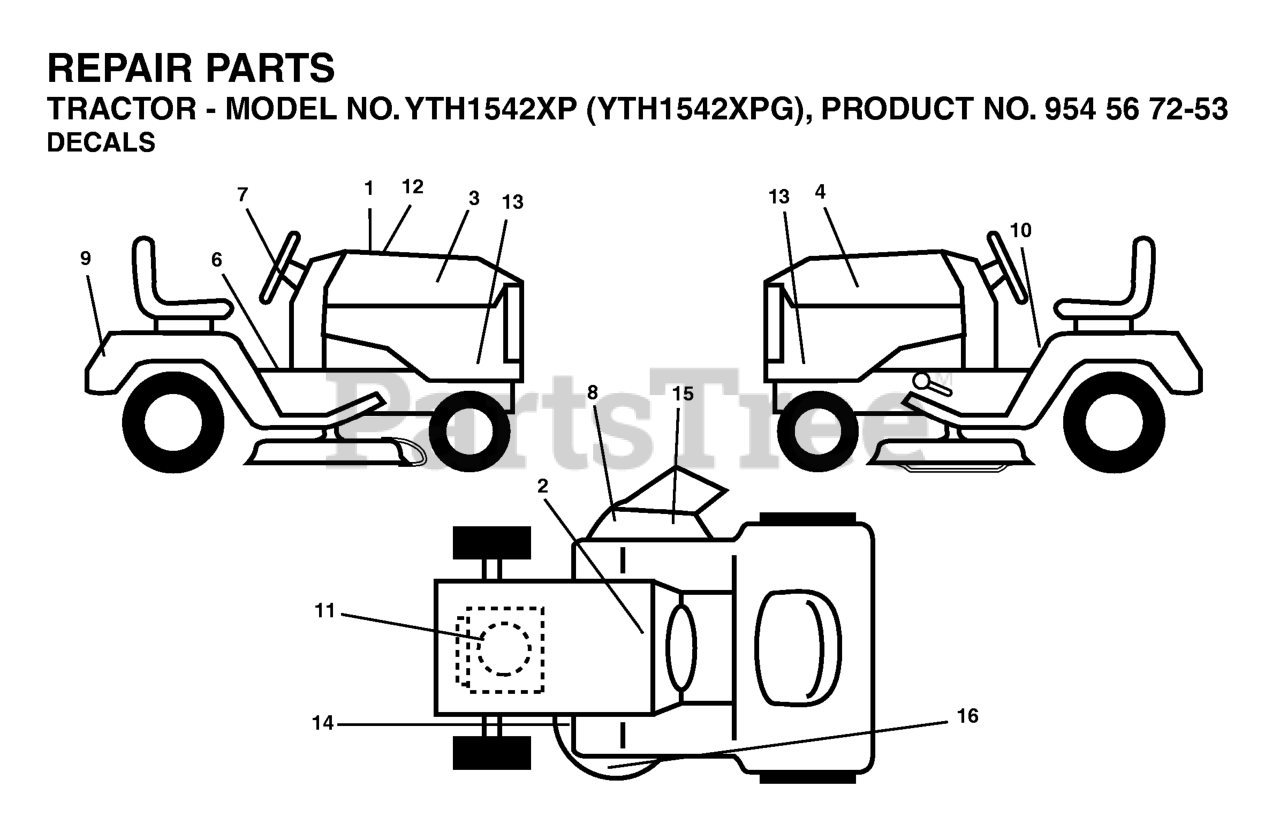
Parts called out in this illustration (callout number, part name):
1	DECAL HOOD CUST. RESP.
2	DECAL BTRY SYMBOLS
3	HOOD DECAL RH
4	HOOD DECAL LH
7	DECAL.WHEEL.STEERING.HUSQ.PERM
8	DECAL.WARN.KEEP.HAND.AWAY
9	DECAL, FENDER
10	DECAL FENDER DANGER
12	DECAL HOOD
13	DECAL HOOD SIDES
14	DECAL V BELT SCHEMATIC
15	DECAL DECK "B" 42"
